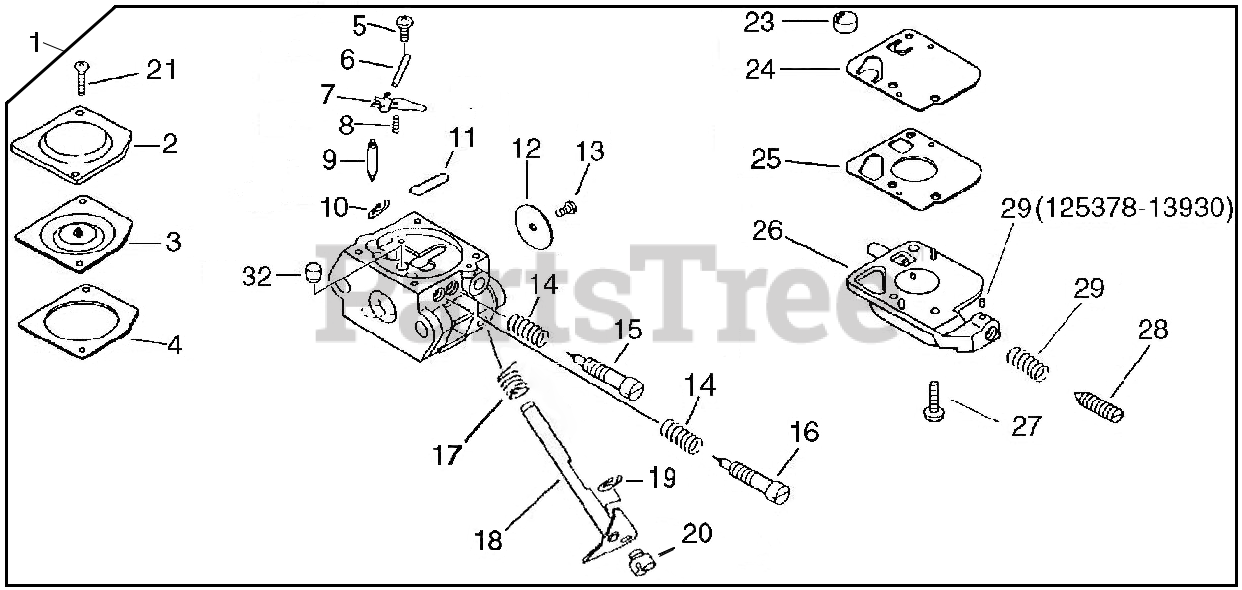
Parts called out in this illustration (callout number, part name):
1	CARBURETOR
2	COVER, METERING DIAPHRAGM
3	DIAPHRAGM
4	GASKET, METERING DIAPHRAGM
6	PIN, METERING LEVER
7	LEVER, METERING
8	SPRING, METERING LEVER
9	VALVE, INLET NEEDLE
11	PLUG, WELCH
12	VALVE, THROTTLE
14	SPRING, NEEDLE
15	NEEDLE, LOW SPEED
16	NEEDLE, HIGH SPEED
17	SPRING, THROTTLE RETURN
18	SHAFT, THROTTLE
23	STRAINER
24	DIAPHRAGM, PUMP
25	GASKET, PUMP
26	COVER, FUEL PUMP
29	SPRING, IDLE ADJUST
32	NOZZLE, CHECK VALVE
